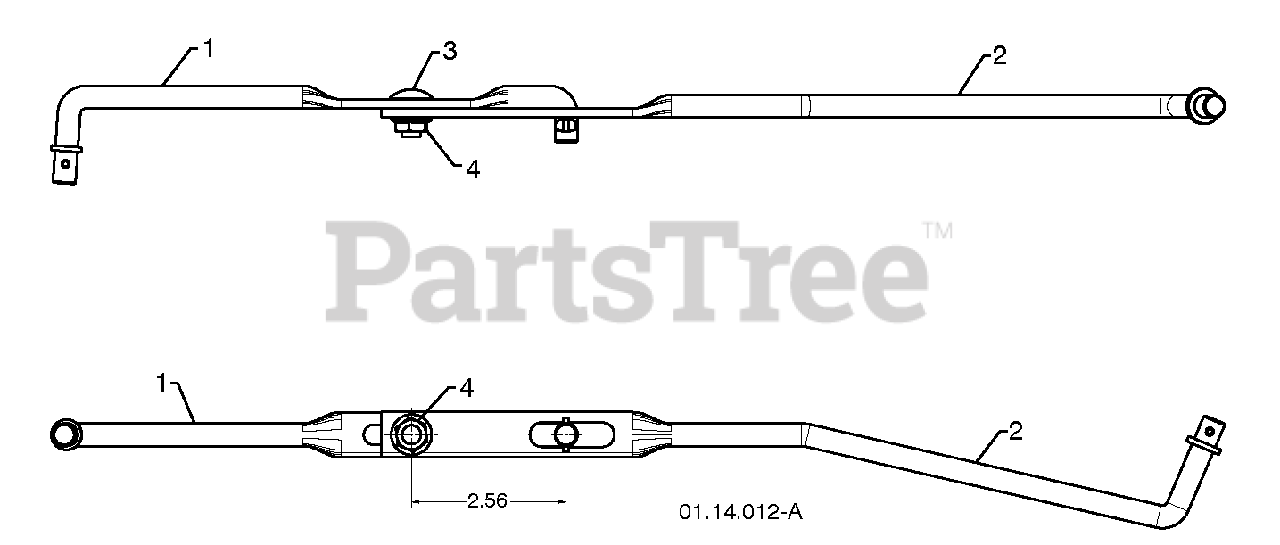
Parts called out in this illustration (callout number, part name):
1	SHIFTER ROD TOP
2	SHIFTER ROD BOTTOM
3	CARRIAGE BOLT 5/16-18 X .75
4	NUT 5/16-18
